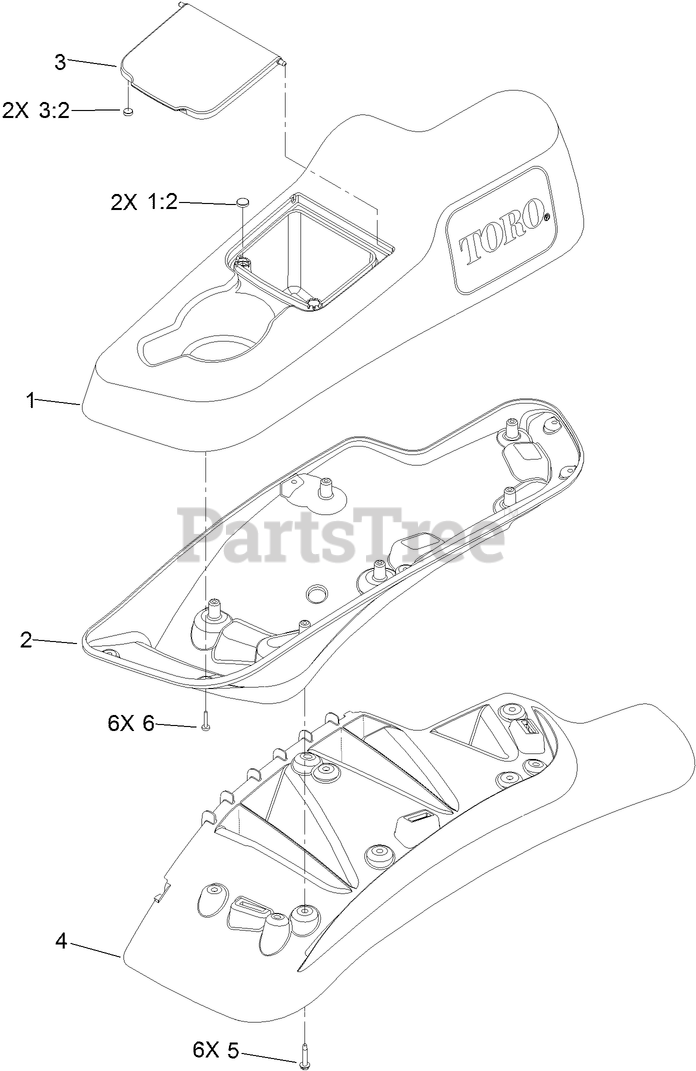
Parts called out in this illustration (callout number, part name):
1	LH CONSOLE TOP ASM
2	LH LOWER CONSOLE ASM
3	LID ASM
3:2	MAGNET
4	FENDER-LH
5	SCREW-THREAD FORMING
6	SCREW-PPH
